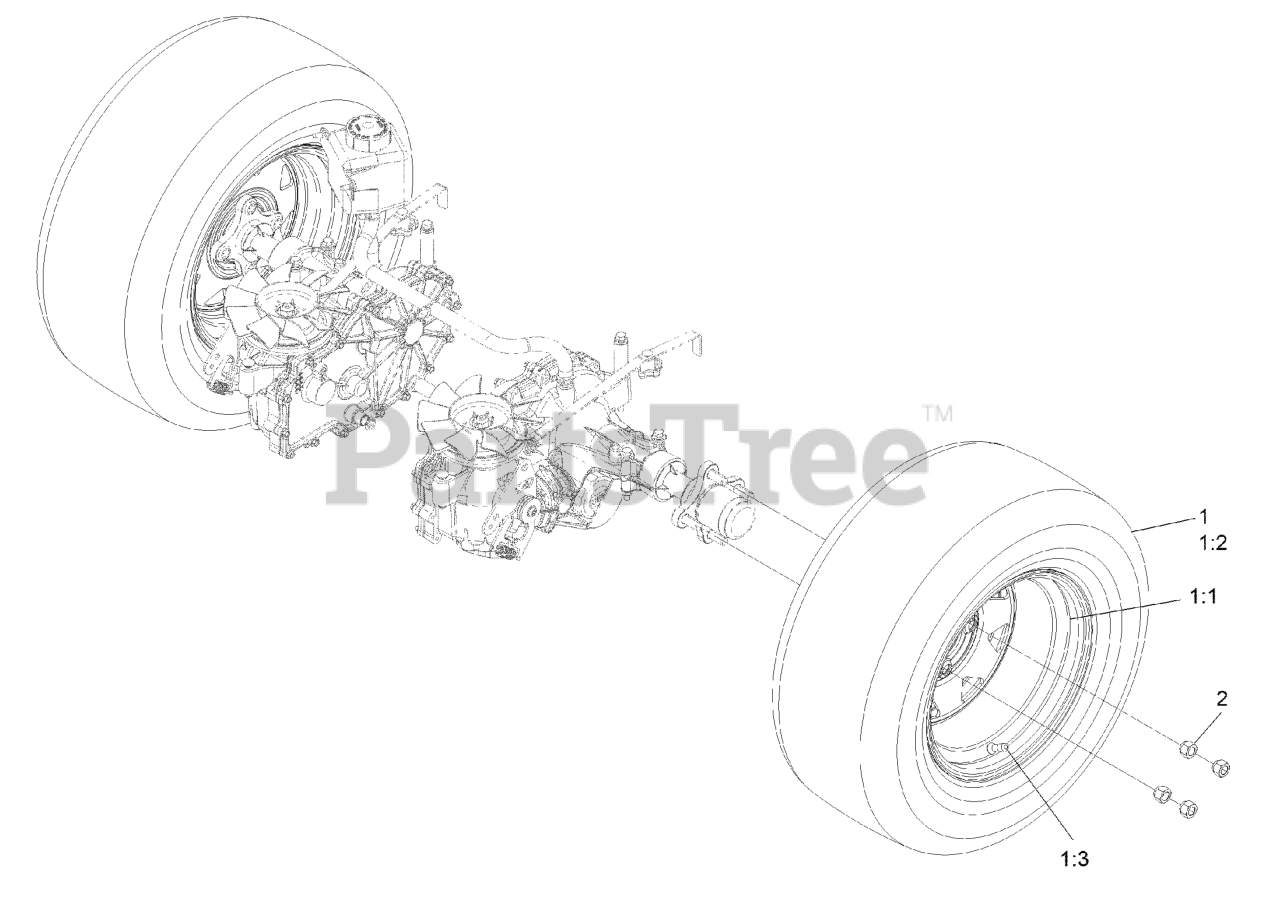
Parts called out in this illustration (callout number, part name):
1	WHEEL AND TIRE ASM
1:1	WHEEL-12X7, 8 SPOKE 4 ON
1:2	TIRE
1:3	Stem-Valve
2	NUT-LUG
